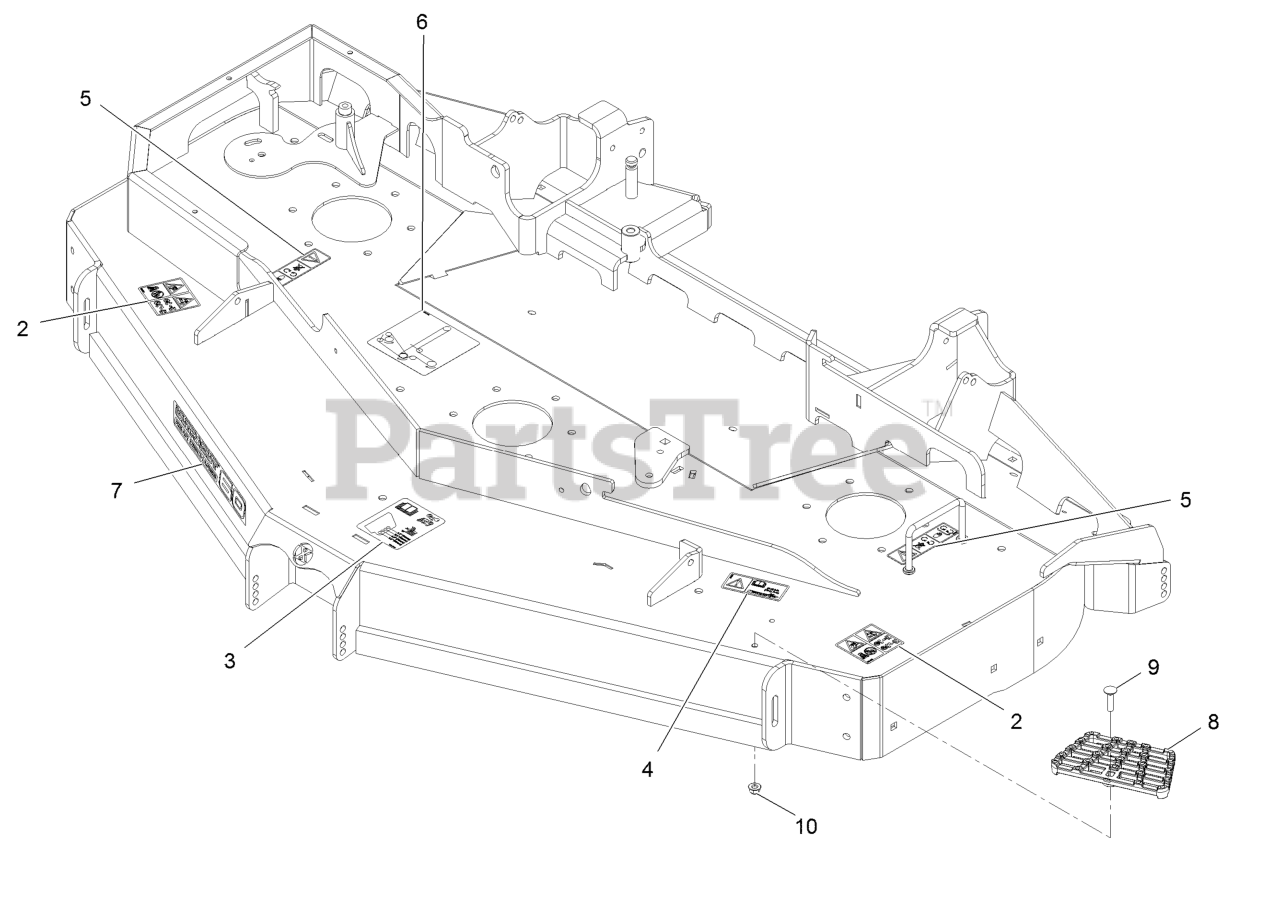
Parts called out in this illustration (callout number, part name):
2	Decal-Danger, Thrown Object
3	Decal-Roller, Anti-Scalp
4	Decal-Bolt Torque
5	Decal-Cover, Missing
6	Decal-Routing, Belt
7	Decal, 60Rd
8	Step-Deck
9	Screw-CARR
10	Nut-HF, NI
